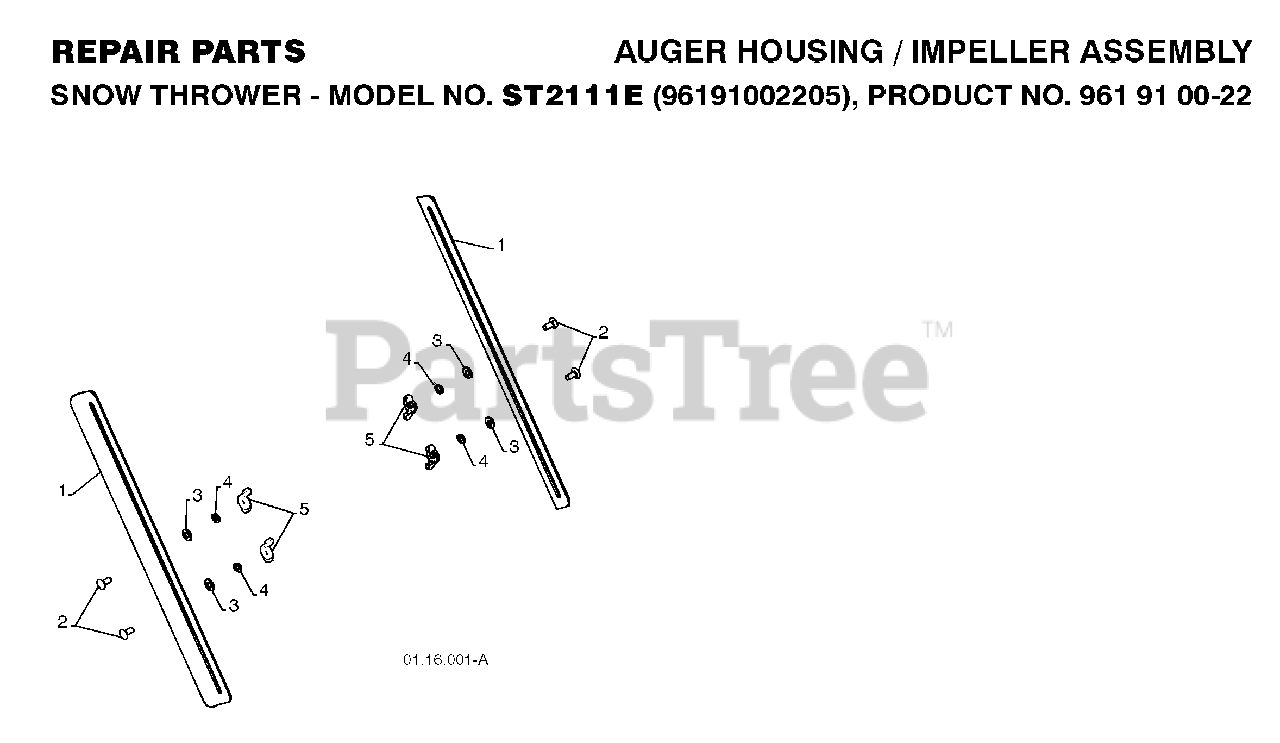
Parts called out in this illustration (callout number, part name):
1	DRIFT CUTTER BAR
3	WASHER, NYLON FRICTION
4	LOCKWASHER
5	NUT WING PM
